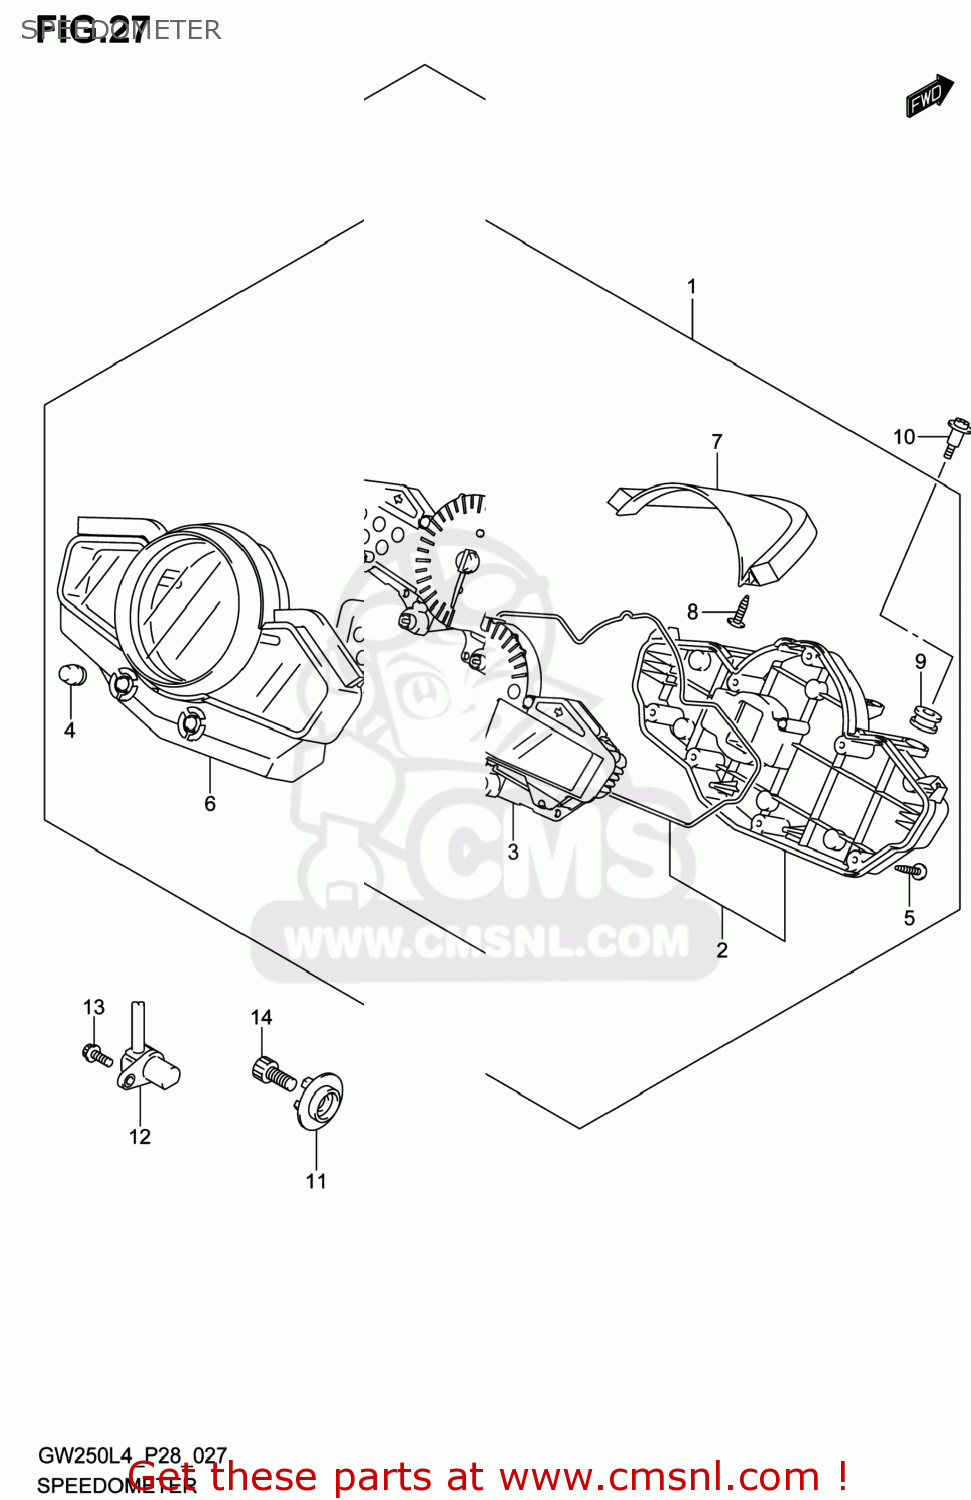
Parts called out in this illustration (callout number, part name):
1	SPEEDOMETER ASSY
2	LWR CASE
3	COMBINATION METER
4	RUBBER
5	SCREW(3X14)
6	UPR CASE
7	COVER
8	SCREW
9	CUSHION,METER
10	SCREW,SPEEDOMETER
11	ROTOR,SPEED
12	SENSOR,SPEED
13	BOLT
14	BOLT
